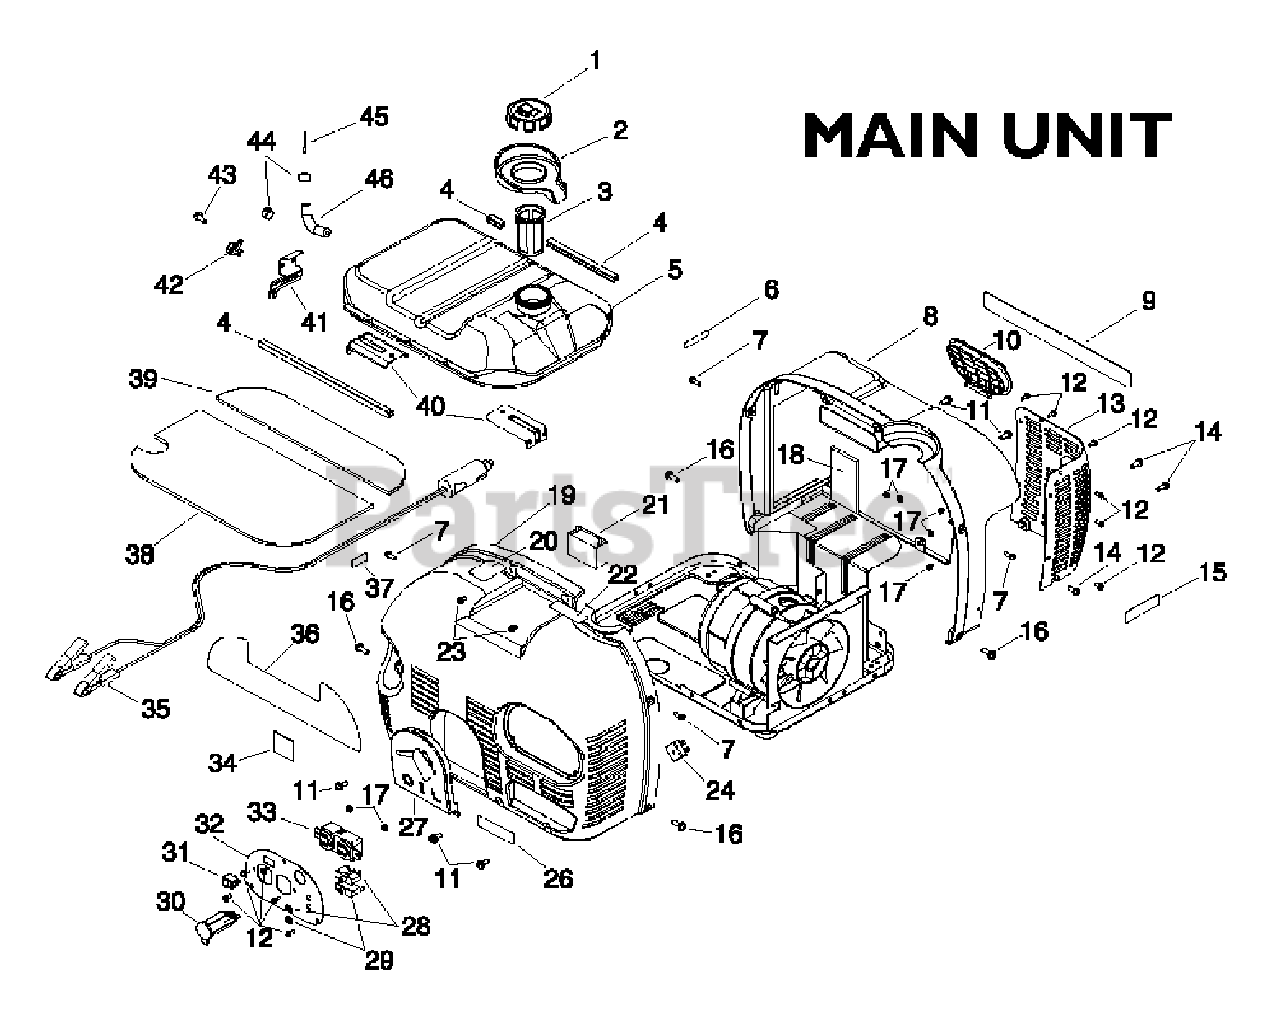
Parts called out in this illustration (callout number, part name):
1	CAP, FUEL
2	PACKING, TANK
3	FILTER, FUEL
4	U-PACKING
5	TANK, FUEL, 4.5L
6	DECAL, CHOKE
7	BOLT, COVER (M5-16)
8	HOUSING, GENERATOR MUFFLER
9	DECAL, WARNING
10	COVER, SPARK PLUG
11	BOLT, COVER (M6-16)
12	PAN HEAD MACHINE SCREW, M4-12 W/FW
13	COVER, MUFFLER, GENERATOR
14	BOLT, MUFFLER COVER (M6-16)
15	DECAL CAUTION HOT
16	BOLT, COVER (M6-20)
17	NUT, M4X0.6 W/FW
18	INSULATION, MUFFLER
19	HOUSING, GENERATOR
20	DECAL, Emission
21	CONDENSER, 300V
22	DECAL, CAUTION FUEL
23	BOLT, COVER (M5-10)
24	DIODE, BRIDGE
26	DECAL, GENERATOR, SNAPPER
27	COVER, OIL FILL
29	CB, 8A, 125V
30	OUTLET, ACCESSORY DC
31	SWITCH, ENGINE ON/OFF
32	PANEL, CONTROL
33	RECEPTACLE, 15A, 125V
34	DECAL, CAUTION OIL
35	CABLE, BATTERY CHARGE
36	DECAL, MODEL
37	DECAL, FUEL SHUTOFF
38	INSULATON, HEATSHIELD, TANK #1
39	INSULATON, HEATSHIELD, TANK #2
40	BRACKET, TANK, FUEL
41	BRACKET, FUEL COCK
42	COCK, FUEL
43	PAN HEAD MACHINE SCREW, M5-10 W/FW
44	CLIP, FUEL HOSE
45	FILTER, FUEL
46	HOSE, FUEL
48	MANUAL-OPERATOR
49	Operator's Manual
